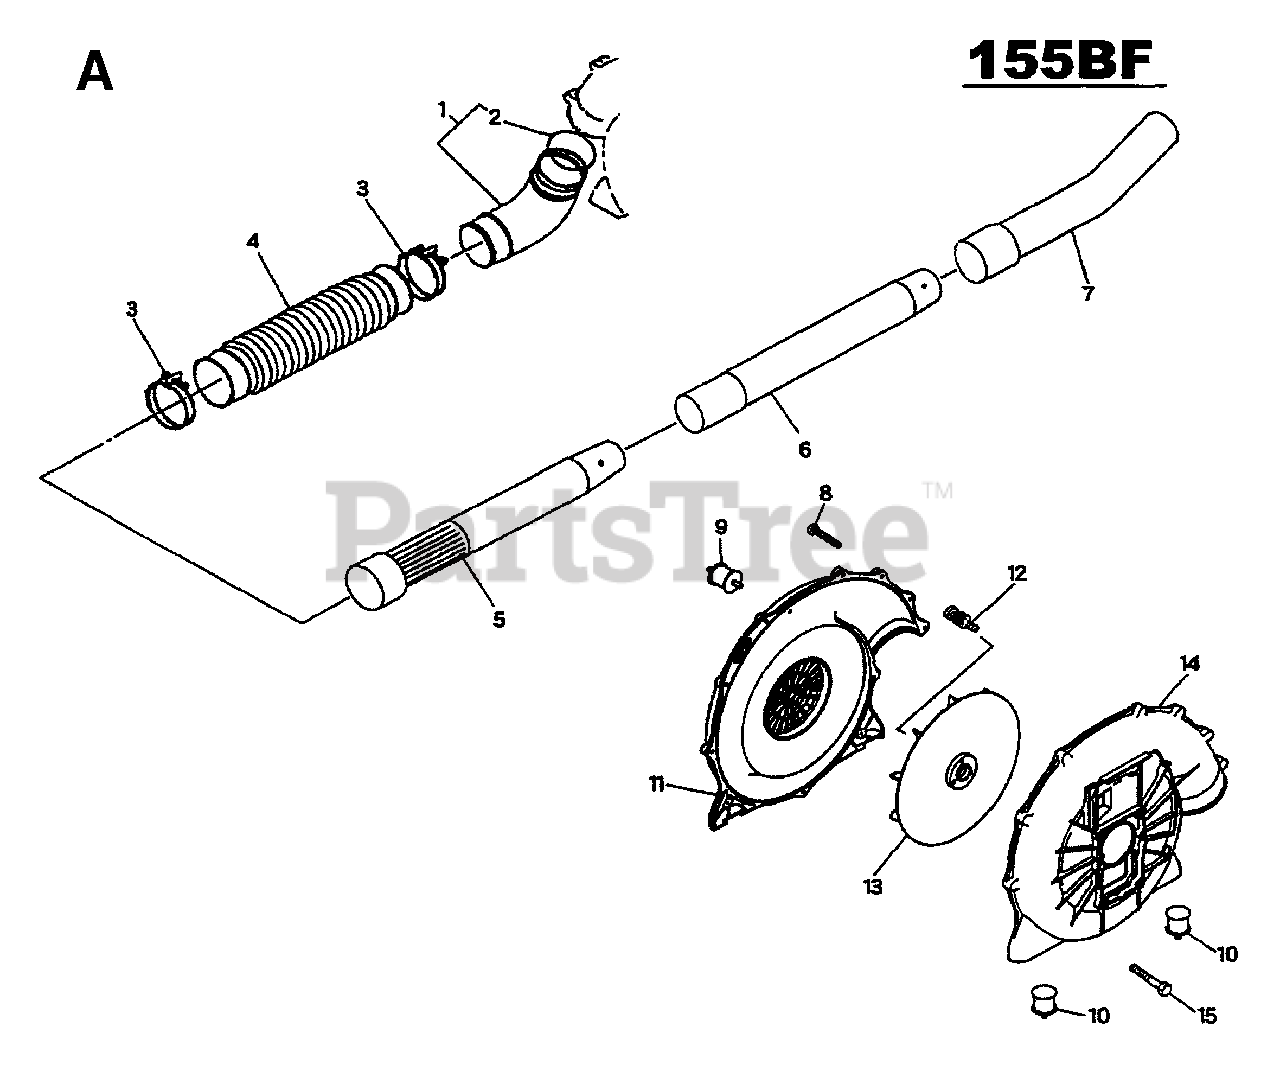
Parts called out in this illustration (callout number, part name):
1	Elbow Pipe Compl.
2	O-Ring
3	Clamp
4	Flexible Pipe
5	Base Pipe
6	Middle Pipe
7	Bend Pipe
8	Tapping Screw (M5x20)
9	Rubber AV Mount
10	Rubber AV Mount
11	Fan Housing
12	Pre-Coat Lock Bolt
14	Fan Housing
15	Pre-Coat Lock Bolt
